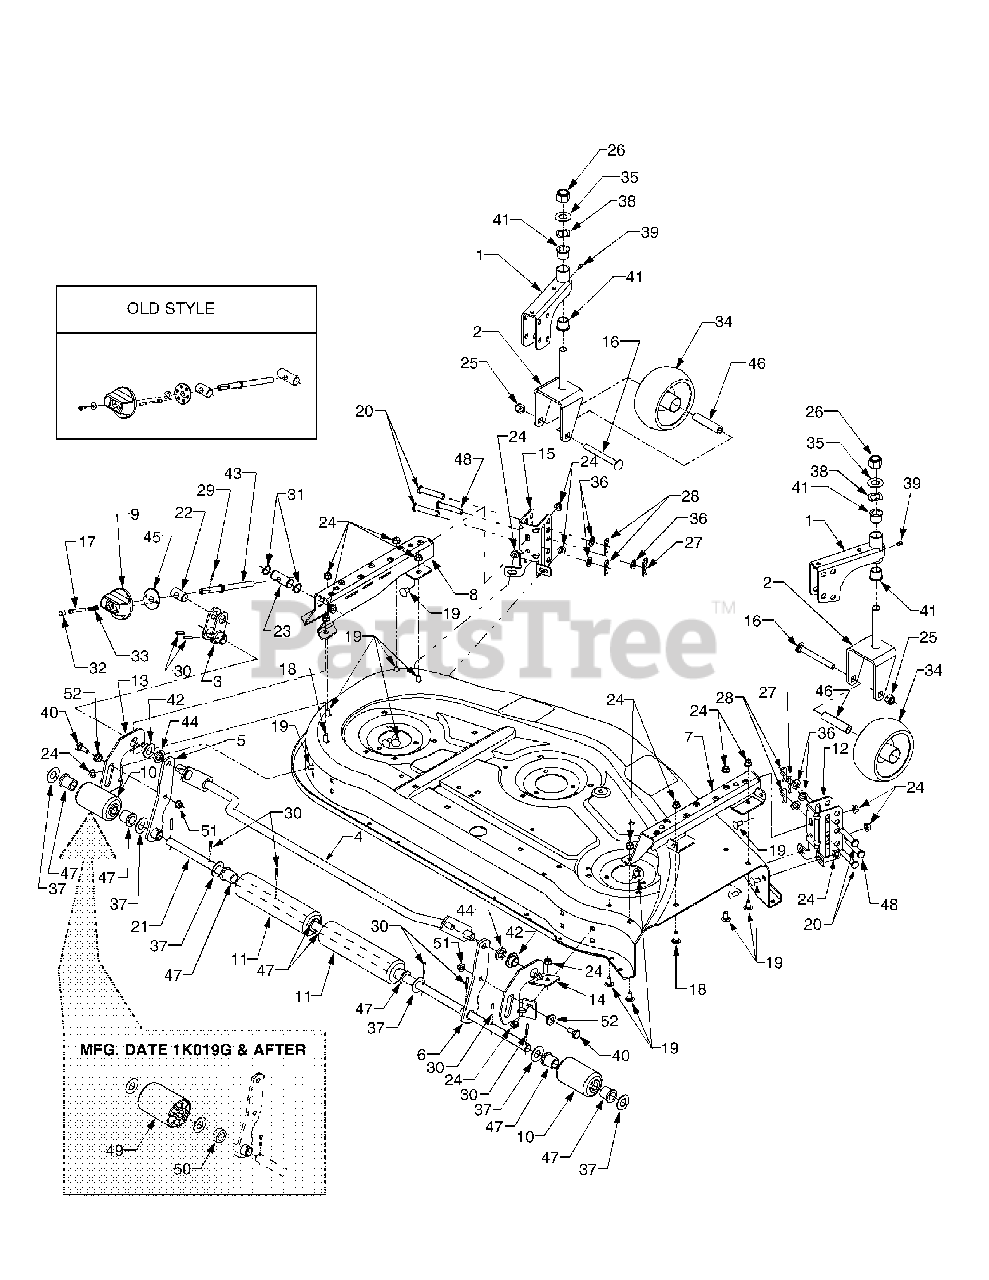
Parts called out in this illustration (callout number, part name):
1	Assembly, Arm - Caster Wheel
2	Assembly, Yoke - Caster Wheel
5	Assembly, Pivot Link (L.H.) Mfg. Date 1K019G & After
6	Assembly, Pivot Link (R.H.) Mfg. Date 1J319G & Before
6	Assembly, Pivot Link (R.H.) Mfg. Date 1K019G & After
7	Assembly, Brace (R.H.)
8	Assembly, Brace (L.H.)
9	Assembly, Knob w/detent pin
10	Roller, (Short) Mfg. Date 1J319G & Before
11	Roller, (Long) Mfg. Date 1J319G & Before
12	Bracket, Height Adjuster (R.H.)
13	Bracket, Guide (L.H.) Mfg. Date 1J319G & Before
13	Bracket, Guide (L.H.) Mfg. Date 1K019G & After
14	Bracket Guide (R.H.) Mfg. Date 1J319G & Before
14	Bracket Guide (R.H.) Mfg. Date 1K019G & After
15	Bracket, Height Adjuster (L.H.)
16	Bolt, Carriage 1/2-13 x 4.5"
17	Screw, Socket Hd Lock 1/4-20 x 2.0
18	Bolt, Carriage 3/8-16 x 1"
19	Bolt, Carriage 3/8-16 x .75"
20	Pin, Clevis
21	Axle, Roller Mfg. Date 1J319G & Before
21	Axle, Roller Mfg. Date 1K019G & After
22	Ferrule, Adjustable
23	Ferrule, Adjust. Thrd, 1/2-13
24	Nut, Flanged Nut 3/8-16
25	Nut, Hex Lock 1/2-13
26	Nut, Hex Lock 3/4-10
27	Pin, Internal Cotter
28	Pin, Internal Cotter
29	Pin, Spirol, .125 x .812
30	Pin, Roll 3/16" Dia. x 1.1"
31	Ring, External Retaining
32	Cap, Tube
33	Spring, Compression
34	Caster, Wheel w/Bearings
35	Washer, Flat .76" I.D.
36	Washer, Flat .535" I.D.
37	Washer, Flat .78" I.D.
38	Washer, Wave .88" I.D.
39	Fitting, Grease
40	Screw, Shoulder Mfg. Date 1J319G & Before
40	Screw, Shoulder Mfg. Date 1K019G & After
41	Bearing, Flange .75" I.D.
42	Bearing, Flange .75" I.D.
43	Screw, Adjustable
44	Spacer, .75 ID x 1.25 OD x .175
45	Hub, Spring Detent
46	Axle, Caster Wheel
47	Bearing, Flange.75" I.D. Powdered Metal
47	Bearing, Flange.75" I.D. Nylatron
48	Pin, Clevis (Mfg. Date 1I018G & After)
49	Roller, Deck Mfg. Date 1K019G & After
50	Spacer, .790 ID x .347 Lg Mfg. Date 1K019G & After
51	Nut, Flaged Nut 3/8-16 Mfg. Date 1J319G & Before
51	Nut, Hex Flange Lock, 5/16-18 Mfg. Date 1K019G & After
52	Bushing, Sq. Hgt Adjust. Mfg. Date 1K019G & After
